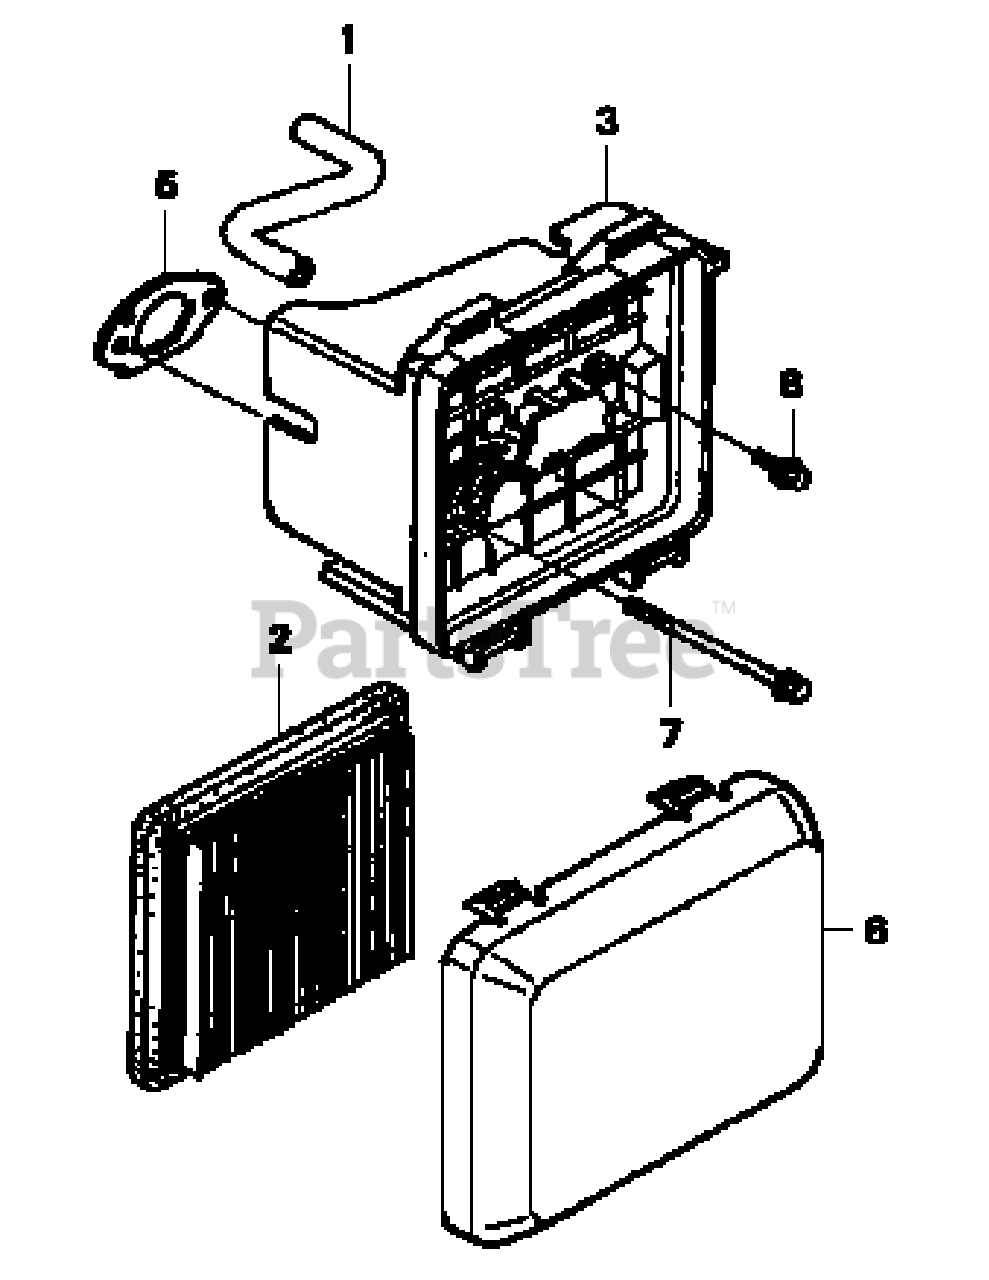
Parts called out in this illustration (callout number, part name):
1	Breather Tube
2	Air Cleaner Element
3	Air Cleaner Case Assy.
5	Air Cleaner Gasket
6	Air Cleaner Cover
7	Flange Bolt (6x86)
8	Flange Bolt (6x14)
